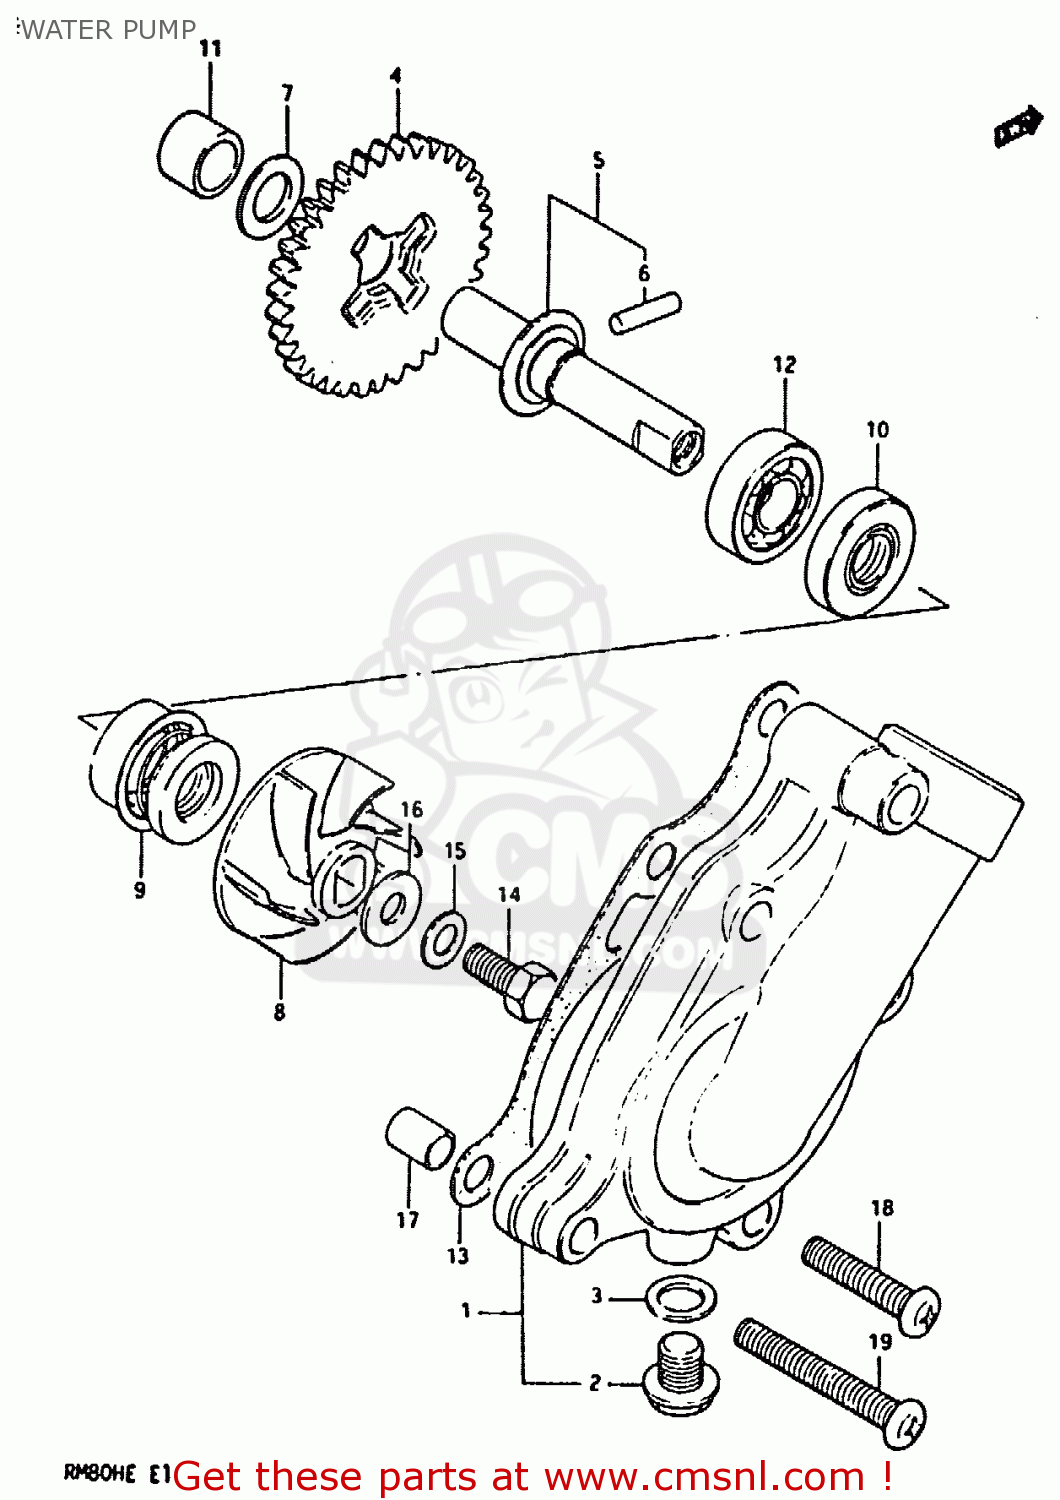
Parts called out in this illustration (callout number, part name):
1	CASE,WATER PUMP
2	BOLT,DRAIN
3	GASKET,DRAIN (NAS)
4	GEAR, DRIVEN (NT:35)
5	SHAFT,WATER PUMP
6	PIN (4X20.8)
7	WASHER,THRUST
8	IMPELLER,WATER PUMP
9	SEAL,WATER PUMP SHAFT
10	SEAL,OIL(10X21X5)
11	BUSH
12	BEARING
13	GASKET,WATER PUMP CASE (MCA)
14	BOLT(6X13)
15	WASHER
16	GASKET (NAS)
17	PIN
18	SCREW
19	SCREW
